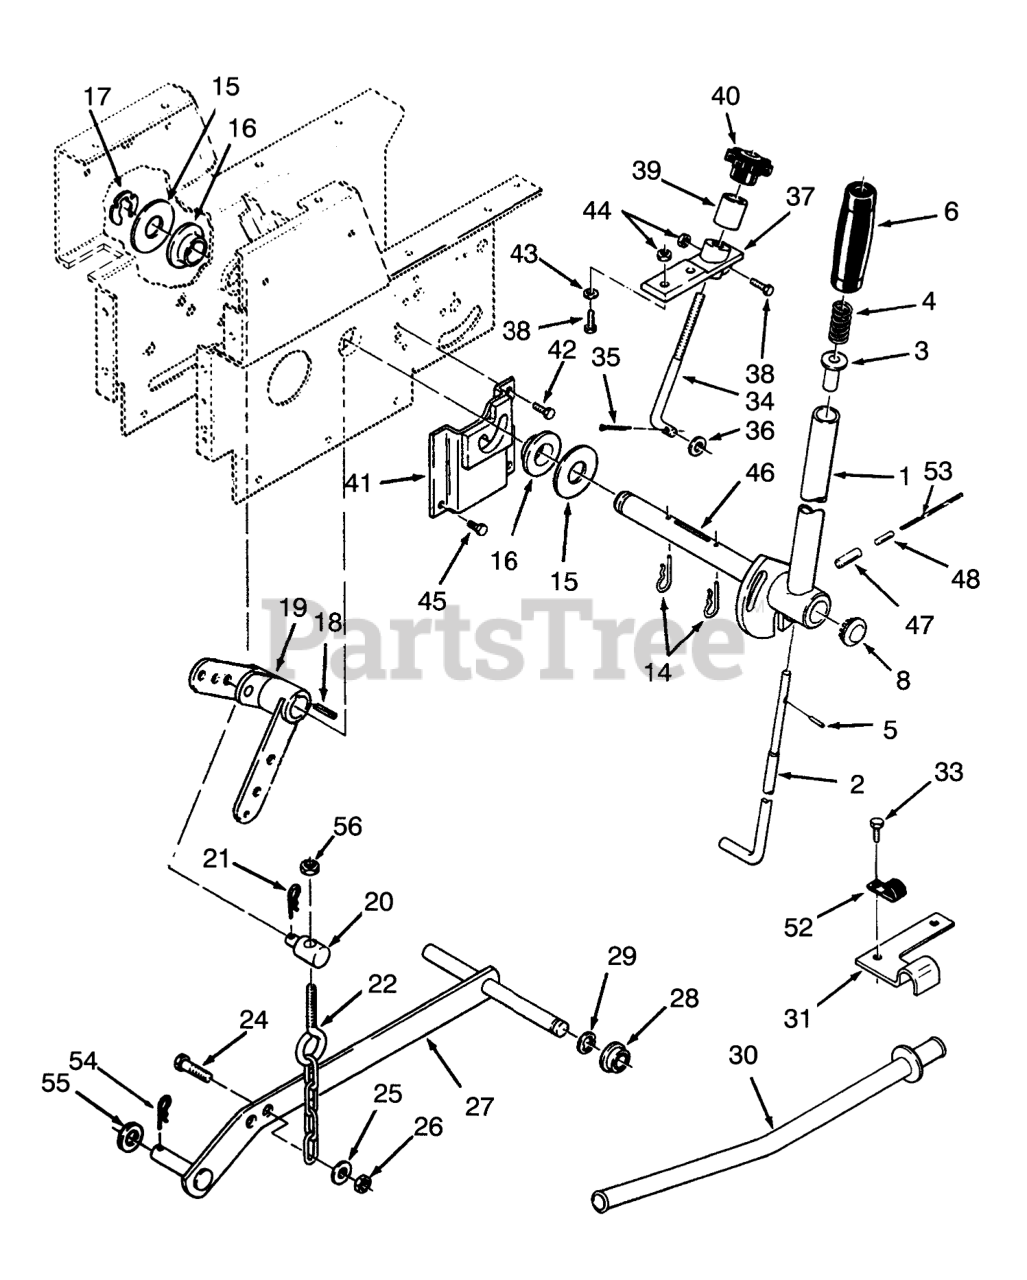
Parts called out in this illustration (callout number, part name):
1	Lever-Lift (Incl. Ref. #46, 47, & 48)
2	ROD-LATCH LIFT
3	RETAINER-SPRING
4	SPRING-COMPRESSION
5	PIN-SPIROL
6	HANDGRIP
8	PLUG
14	Pin-Cotter
15	WASHER-FLAT
16	BEARING-FLANGE
17	Retainer
18	KEY-SQUARE
19	LIFT LEVER ASM
20	TRUNNION-LIFT
21	PIN-HAIR
22	CHAIN-LIFT
24	SCREW-HH
25	WASHER-PLAIN
26	NUT-LOCK, NI
27	Bar-Lift
28	BUSHING
29	E Ring
30	TUBE ASSY COMPLET R
31	CLAMP-CONDUIT R
33	SCREW-HH, LOCK
34	ROD-HEIGHT CONTROL
35	PIN-COTTER
36	WASHER-FLAT
37	Casting
38	SCREW-HH
39	Sleeve
40	KNOB-LIFT CONTROL
41	Latch Bracket
42	Bolt
43	WASHER-PLAIN
44	NUT-LOCK, NI
45	Bolt
46	SHAFT-LIFT LEVER
47	PIN-SPRING
48	PIN-ROLL
52	CLIP
53	Lock Wire
54	Hairpin Cotter
55	WASHER-FLAT
56	NUT-LOCK, NI
